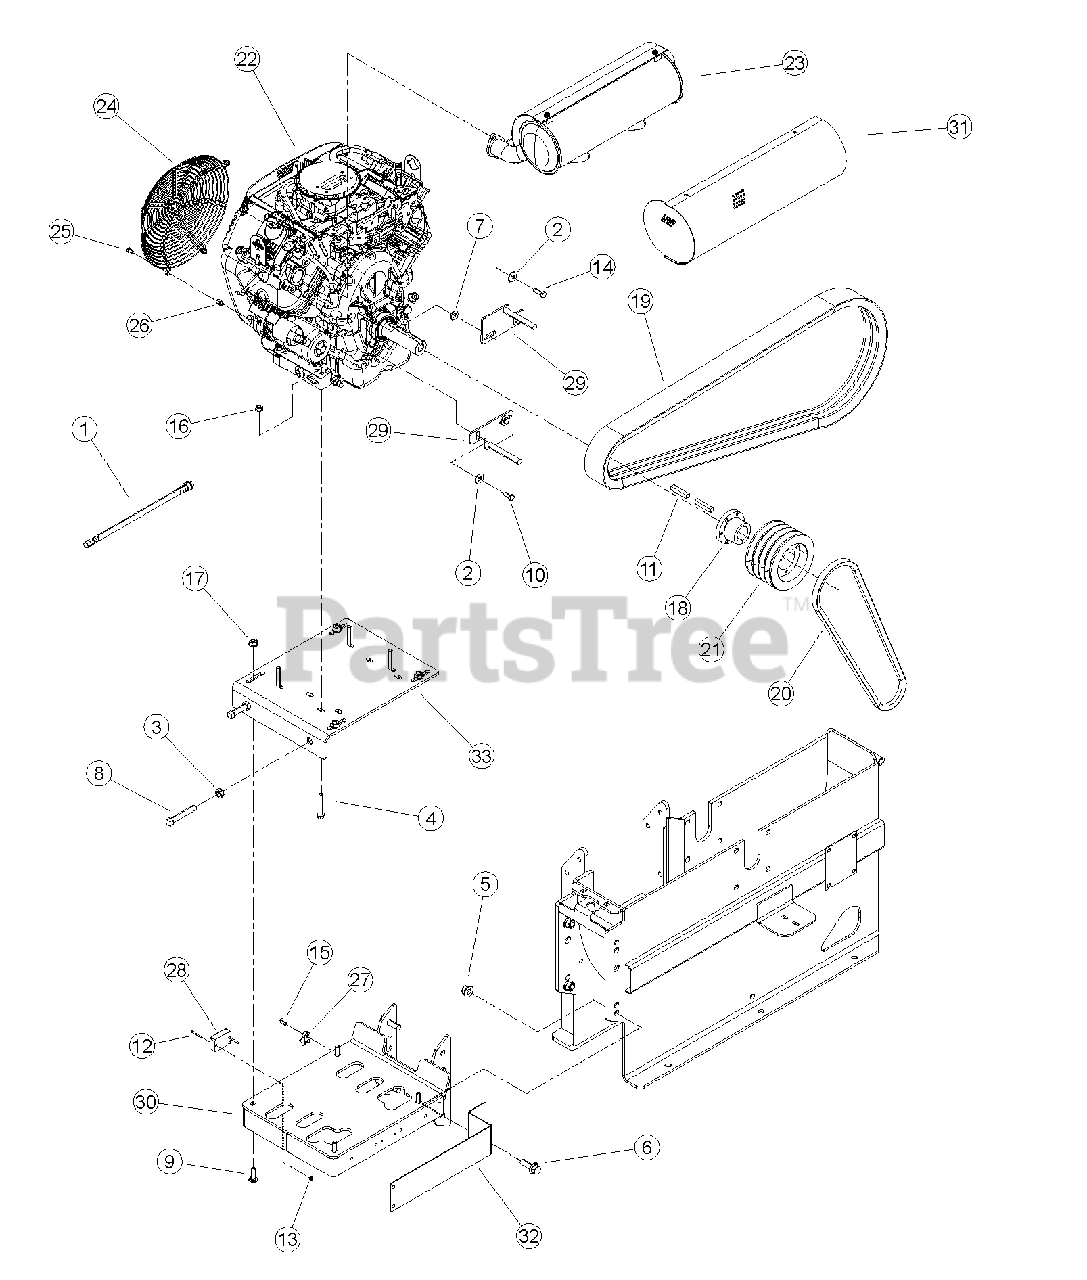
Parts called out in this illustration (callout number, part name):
1	HOSE ASSEMBLY, CRANKCASE DRAIN
2	WASHER, 3/8" FLAT ZP
3	NUT, 1/2 NC ZP JAM
4	BOLT, 5/16 X 2-1/4 FLANGE NC
5	NUT, 1/2-13 NYLOCK FLANGE
6	BOLT, 1/2-13 X 1-1/2 GR5 FLANGE NC
7	WASHER, 5/16" FLAT ZP
8	SETSCREW, 1/2 X 3 SQ HD 1/2 DOG PT
9	BOLT, 3/8 X 1-1/4" GR5 CRG NC ZP
10	BOLT, 5/16-24 X 3/4" GR5 HHCS ZP
11	KEY, 3/8" SQ X 2" LG PLAIN
12	SCREW, #6-32 X 1-1/4" PHP HD
13	NUT, #6-32 NYLON LOCK ZP
14	NUT, 5/8-32 JAM
15	RIVET, AL BLIND 1/4 X 3/4 DOME HEAD
16	NUT, 5/16-18 NYLOCK-FLANGE
17	NUT, 3/8-16 NYLOCK FLANGE
18	BUSHING, SD 1-7/16"
19	BELT, 3B83 BANDED
20	BELT, BX44
21	SHEAVE, 4B5.2 SD
22	ENGINE, BRIGGS 35 HP
23	MUFFLER, BRIGGS 35 HP
24	GUARD, WIRE FLYWHEEL BRIGGS
25	SCREW, FLYWHEEL GUARD BRIGGS
26	NUT, FLYWHEEL GUARD BRIGGS
27	CLAMP, CABLE MOUNT
28	METER, TACH/HOUR
29	WELDMENT, BELT KICKER
30	WELDMENT, ENGINE BASE
31	WELDMENT, SHIELD HEAT
32	SHIELD, HYD PUMP
33	WELDMENT, ENGINE MOUNT PLATE
